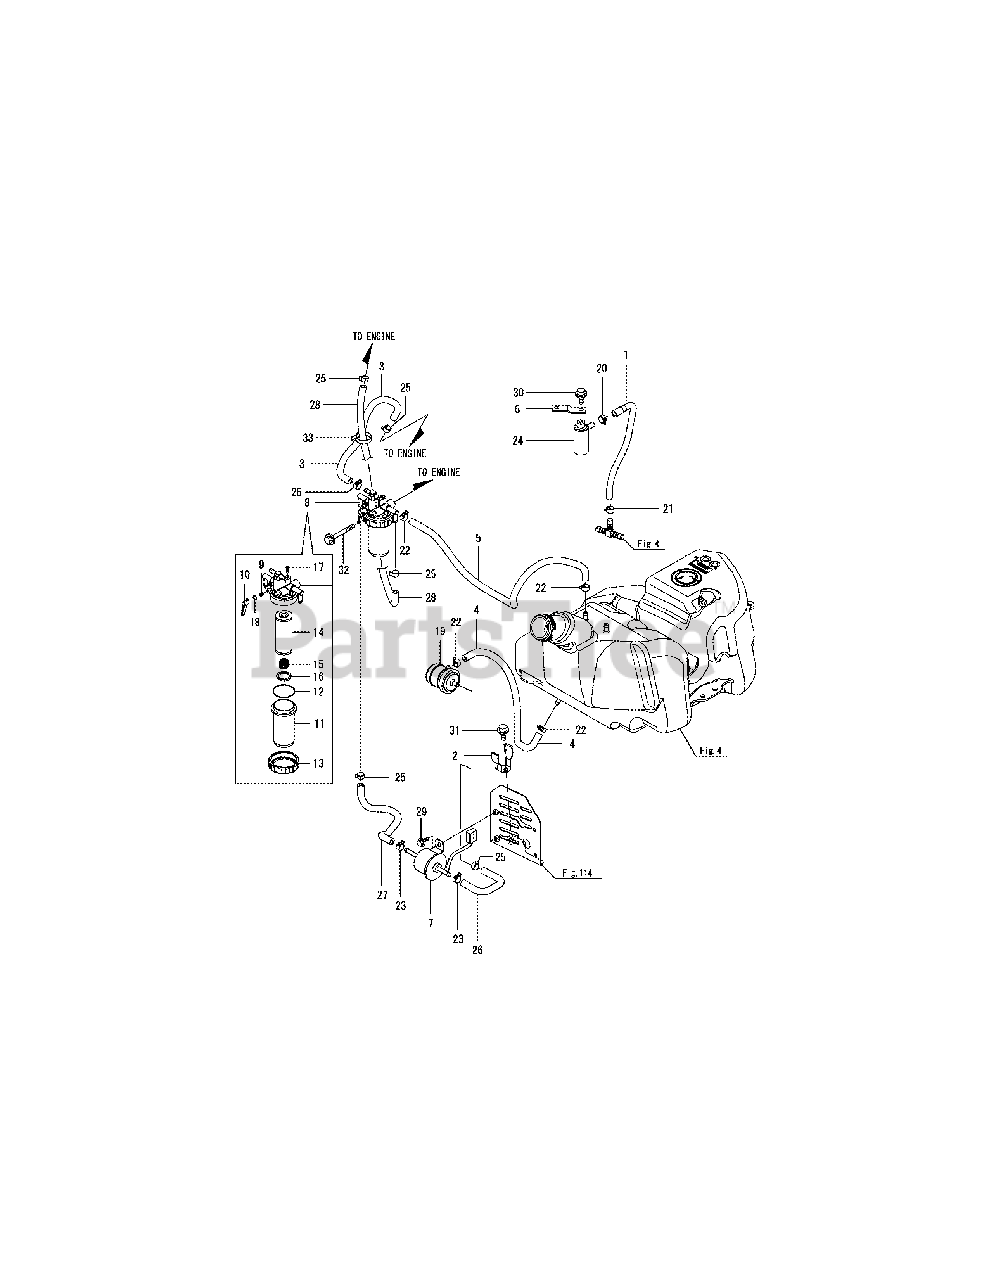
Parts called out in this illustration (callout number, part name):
1	Hose, Air Vent
3	Fuel Pipe 7.3X400
6	Support, Breather
7	Pump Assy, Fuel Feed
8	Filter Assy, Fuel
13	Ring, Retaining
14	Element, Strainer
15	Spring, Screen
18	O-Ring 1A P-10A
26	Hose 7.3X150,Braided
27	Hose, 7.3 X 180
28	Fuel Pipe 7.3X350
29	Bolt M 6X 16 Plated
30	Bolt M 8X 12 Plated
31	Bolt M 8X 12 Plated
32	Bolt M 8X 65 Plated
